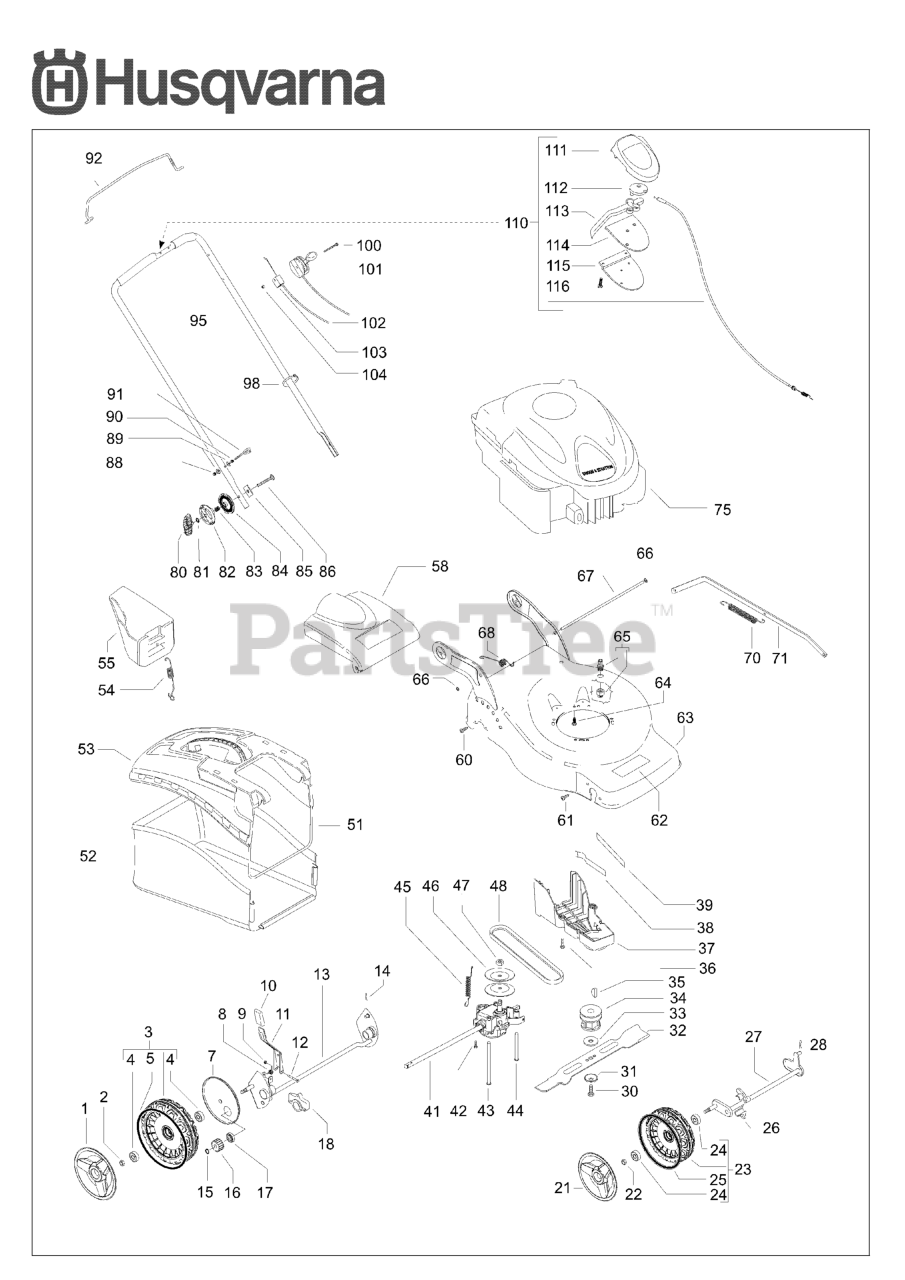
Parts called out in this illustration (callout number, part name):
11	LIFTING LEVER ASSY FOR REAR AX
102	BRAKE WIRE
111	CASE.TOP.GRAY
112	PULLEY.CAM.DRIVE.CONTROL.HV
113	LEVER
114	CASE BOTTOM
115	BRACKET, DRIVE CONTROL
116	SCREW, PHILLIPS HEAD 10 X 5/8
